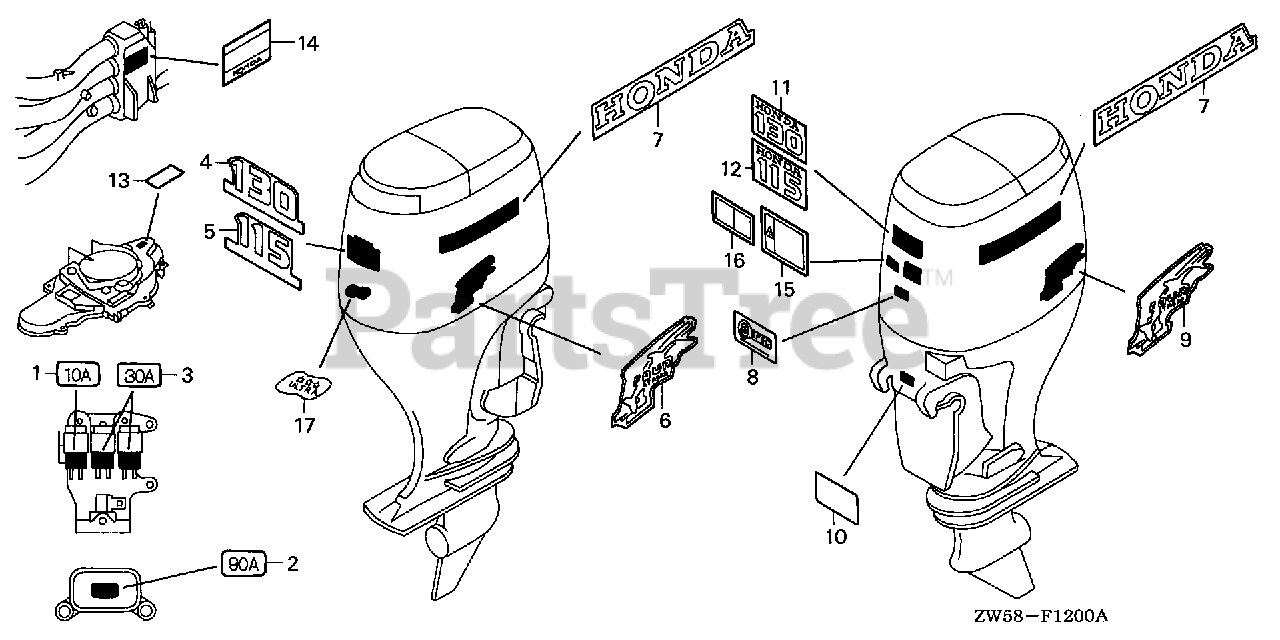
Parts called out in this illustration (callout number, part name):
1	MARK, FUSE (10A)
2	MARK, FUSE (90A)
3	MARK, FUSE (30A)
5	MARK, RR. (BF115)
6	MARK, SIDE (R. SIDE)
7	MARK, SIDE STRIPE (HONDA)
8	MARK (E-SPEC)
9	MARK, SIDE
12	MARK, FR. EMBLEM (BF115)
13	LABEL, OIL CAUTION (ENGLISH)
14	MARK, MUFFLER
15	LABEL, OPERATOR CAUTION (ENGLISH)
15	LABEL, WARNING OPERATOR
